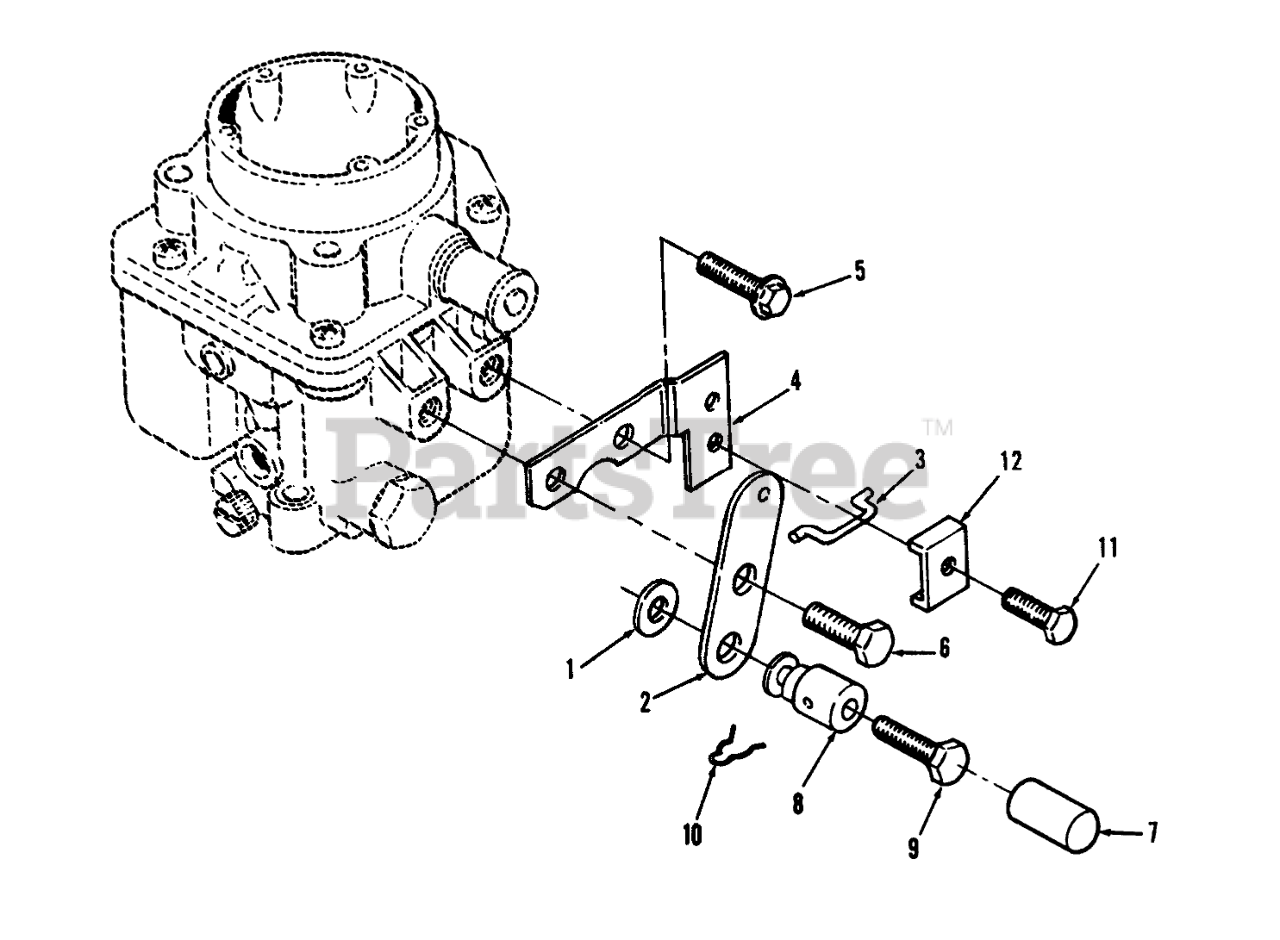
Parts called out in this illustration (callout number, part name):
1	Washer
2	SWIVEL-CHOKE
3	LINK-CHOKE
4	BRACKET
5	Bolt
6	MACHINE SCREW
8	SWIVEL
9	Bolt
10	PIN-COTTER
11	Bolt
